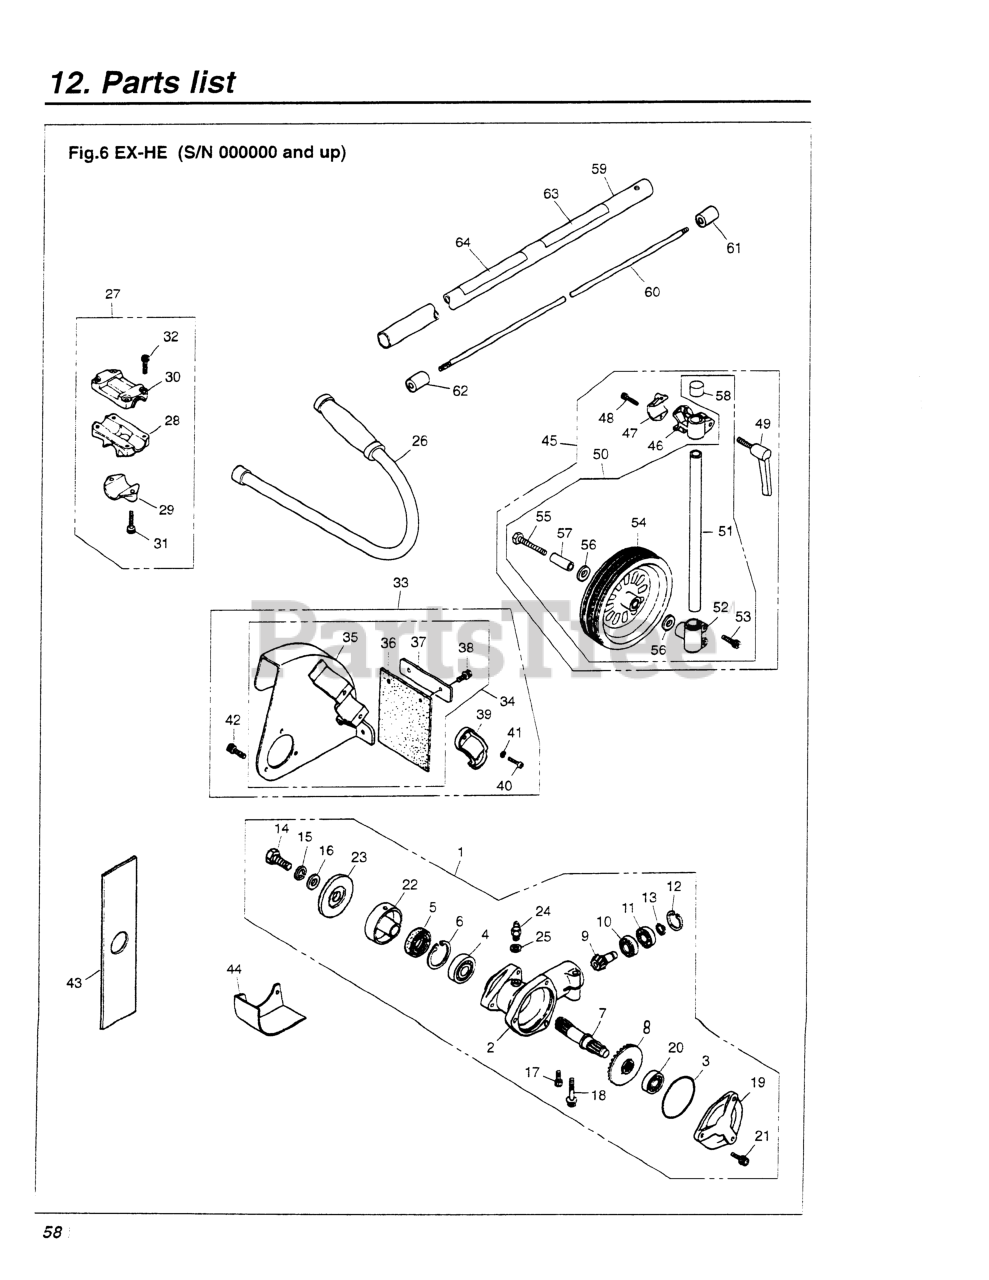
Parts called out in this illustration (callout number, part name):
3	O-RING
5	SEAL, OIL
6	RING, SNAP, M32 x 1.2
7	SHAFT, GEAR
8	GEAR
9	PINION
10	BEARING (RPLS T3403-13530)
11	BEARING (RPLS T3300-13531)
12	RING, SNAP, M24 x 1.2
13	RING, SNAP (RPLS T3300-13330)
14	BOLT, LH
15	WASHER (RPLS 3180-13270)
16	WASHER, M8 x 2.3 (RPLS -20823)
17	BOLT, M5 x 12
18	BOLT, M6 x 1.35
19	COVER
20	BEARING (RPLS T3403-13510)
21	BOLT
22	HOLDER (A)
23	HOLDER (B)
24	FITTING, GREASE
25	WASHER, M6 X .8
26	HANDLE, J
27	BRACKET ASSY (REPLACES -14100)
29	CAP, LOWER
30	CAP, UPPER (RPLS -14191)
31	BOLT, M5 X 22
32	BOLT, M5 X 25
36	PLATE (RUBBER)
37	PLATE (REPLACES -24130)
38	BOLT, M5 X 12
40	BOLT, M6 X 18
41	WASHER, M6 X 15
42	BOLT
43	BLADE, EDGER (RPLS 147315)
44	COVER (CAN USE 6367-96110)
45	WHEEL ASSY COMP (RPLS -25000)
46	BRACKET
47	CAP, LOWER
48	BOLT, M5 X 22
49	LEVER
50	WHEEL ASSY (RPLS -25100)
51	PIPE
53	BOLT, M6 X 25
54	WHEEL
55	BOLT (REPLACES -81060)
56	WASHER, M10 x 1.6
57	SPACER, PIPE
58	CAP
59	PIPE COMPLETE
60	SHAFT
61	JOINT, SHAFT (RPLS -12240)
62	SPACER
63	PLATE, NAME (RPLS.T3052-12510)
64	PLATE, CAUTION
